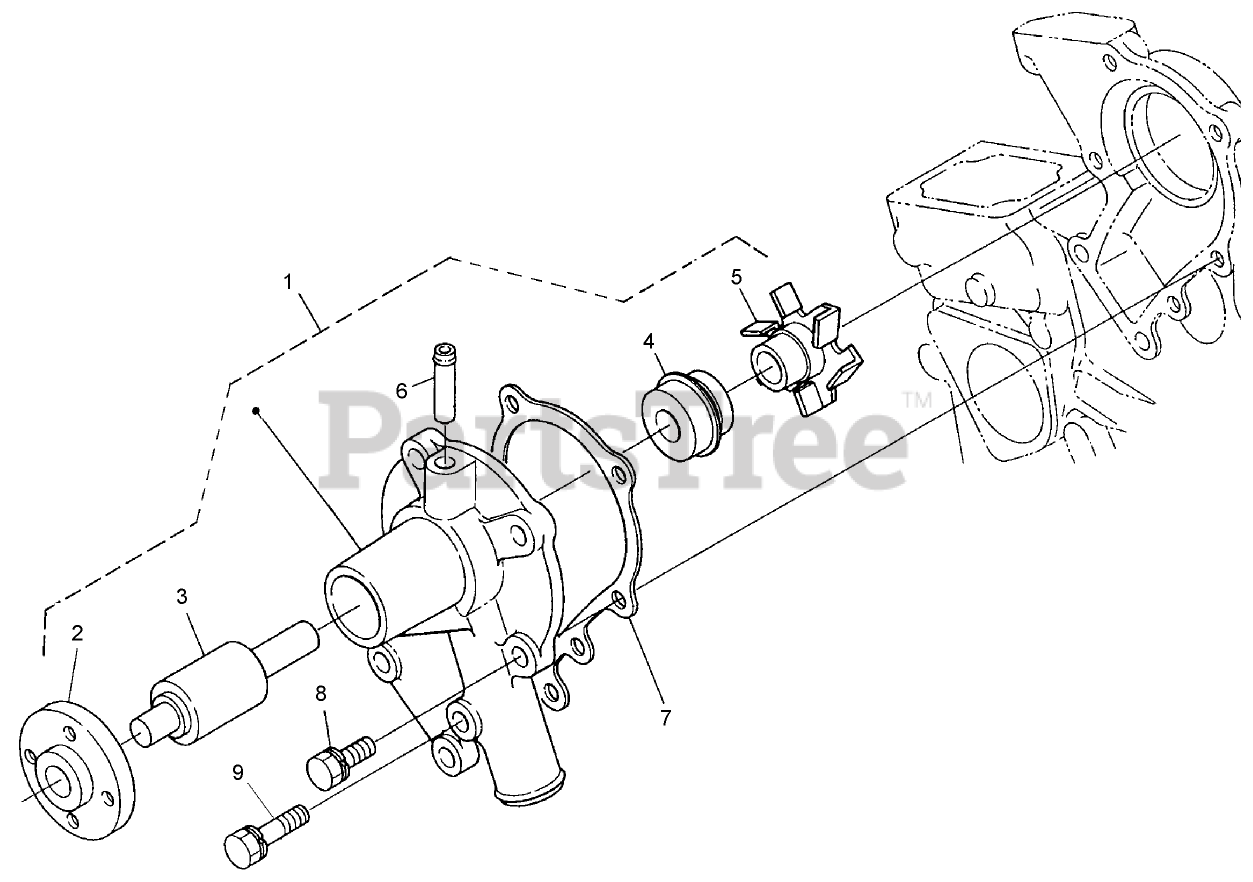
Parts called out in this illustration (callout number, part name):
1	WATER PUMP ASM
2	FLANGE-PUMP, WATER
3	BEARING-BALL
4	WATER PUMP SEAL ASM
5	IMPELLER-PUMP, WATER
6	PIPE-RETURN, WATER
7	GASKET-PUMP, WATER
